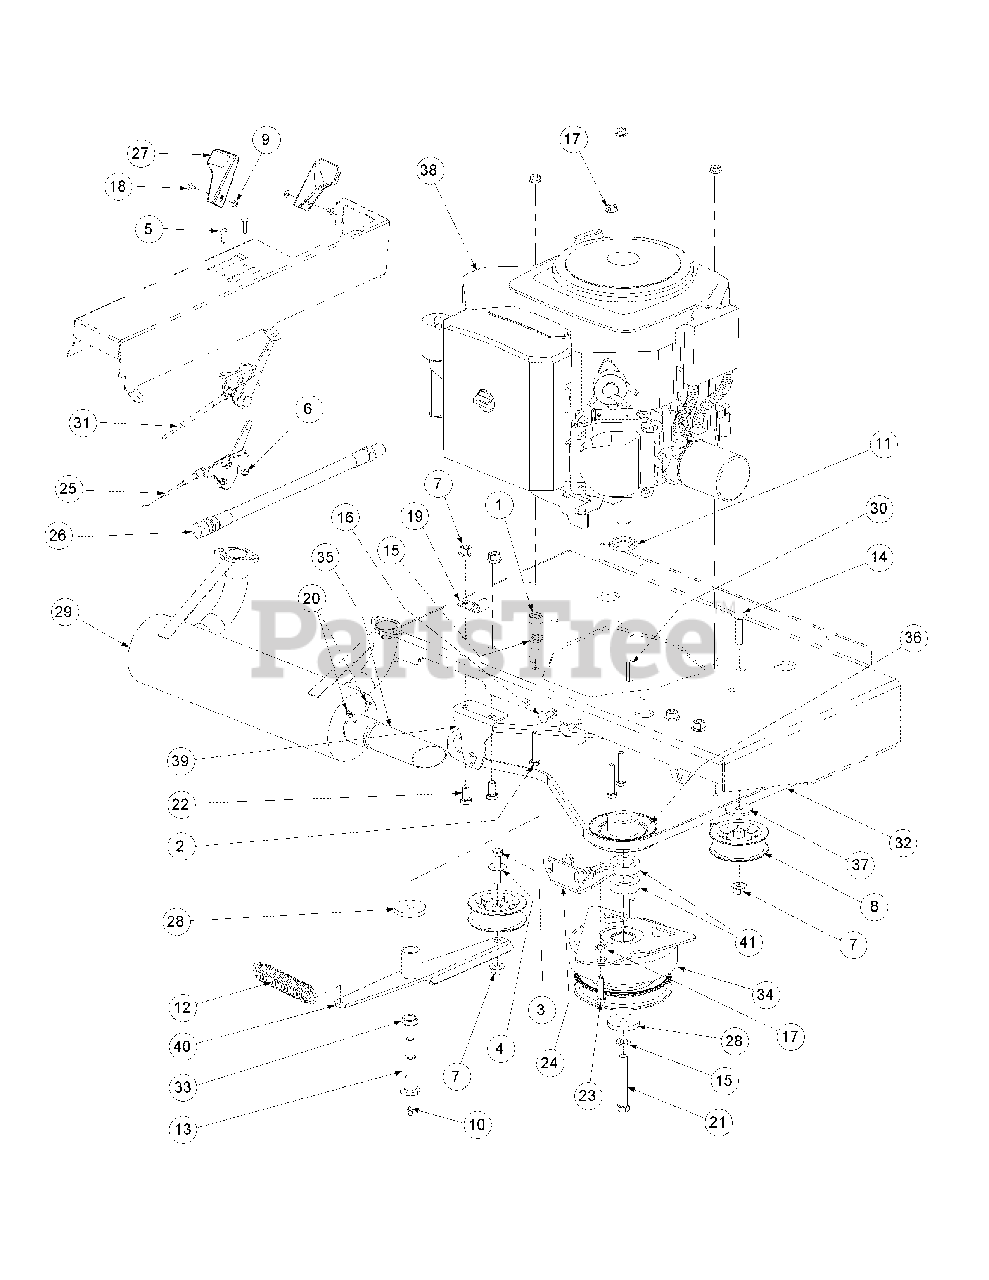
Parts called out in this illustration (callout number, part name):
1	Hex Nut, 7/16-14
2	HHCS, 5/16-18, 1-3/4
3	Capscrew, 3/8-16 x 1-3/4
5	Round Hd. Machine Screw, 10-32 x 3/4
6	Lock Nut, Nylon Insert, 10-32
7	Flange Lock, Hex Nut, 3/8-16
8	Idler Pulley w/ Adaptor
9	Nut Washer, W/Star, 8-32
10	Grease Fitting, 1/4-28 x 3/16
11	Engine Spacer
12	Extension Spring, 1.0 OD x 5.00
13	Shoulder Screw, 7/16-14
14	Hex Carriage Screw, 3/8-16, 1.75
15	Lock Washer, 7/16
16	Carriage Bolt:5/16-18 x 3/4
17	Hexflange Lock Nut, 5/16-18
18	Machine Screw, 8-32, .375
19	Clip, Heat Shield Cable
20	Tube Clamp, 1.375
21	Capscrew, 7/16-20 x 3.00
22	Hex Cap Screw, 3/8-16, .750
23	Hex Cap Screw:5/16-18 x 1-1/4
24	Retainer Clutch Assembly, Ogura
25	Throttle, Control Cable, 45.0
26	Oil Drain Hose
27	Control Throttle Knob
28	Flat Washer, 7/16 IDx 1.750 OD x .250T
29	23HP Kohler Exhaust
30	Key, 1/4 x 1/4 x .875
31	Choke, Control Cable, 38.0
32	V-Belt, 56.00
33	Spacer, .635 ID x .28
34	Electric Clutch
35	Muffler Accessory Exhaust Tube
36	Transmission Drive Pulley (use with 00023821 spacers)
37	Washer, 5/16-18
38	23HP Kohler Engine
39	Neutral Lock Mounting Bracket
40	Engine Idler Arm Assembly Includes:
41	Spacer, 1.015 ID x 1.62 OD x .50 (use with 01007339 pulley)
